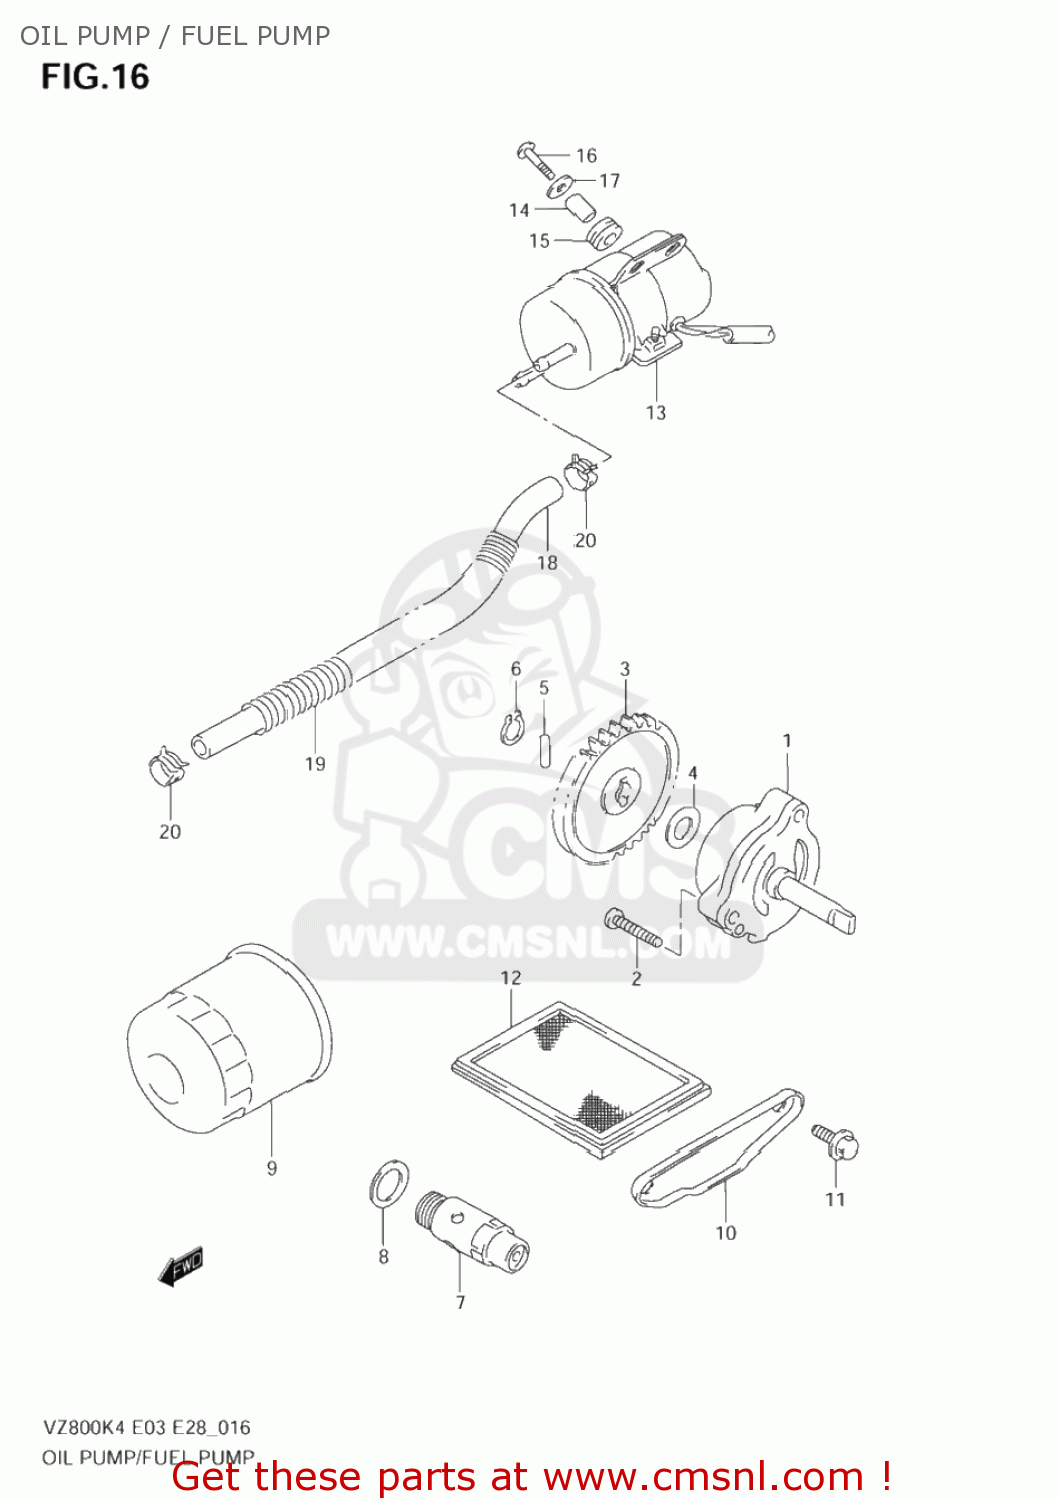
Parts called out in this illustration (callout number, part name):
1	PUMP ASSY,ENGINE OIL
2	SCREW
3	GEAR,OIL PUMP DRIVEN(NT:34)
4	SHIM(10X18X0.5)
5	PIN(4X15.8)
6	CIRCLIP,10MM
7	VALVE ASSY,OIL RELIEF
8	GASKET(16X22X2) (NAS)
9	FILTER ASSY,EN
10	CAP,OIL STRAINER
11	BOLT 6X12
12	STRAINER,ENGINE OIL
13	PUMP ASSY,FUEL
14	SPACER(6.5X9X9)
15	CUSHION
16	SCREW(6X20)
17	WASHER(6.5X20X1.2)
18	HOSE(7X12X600)
19	SPRING
20	CLIP
